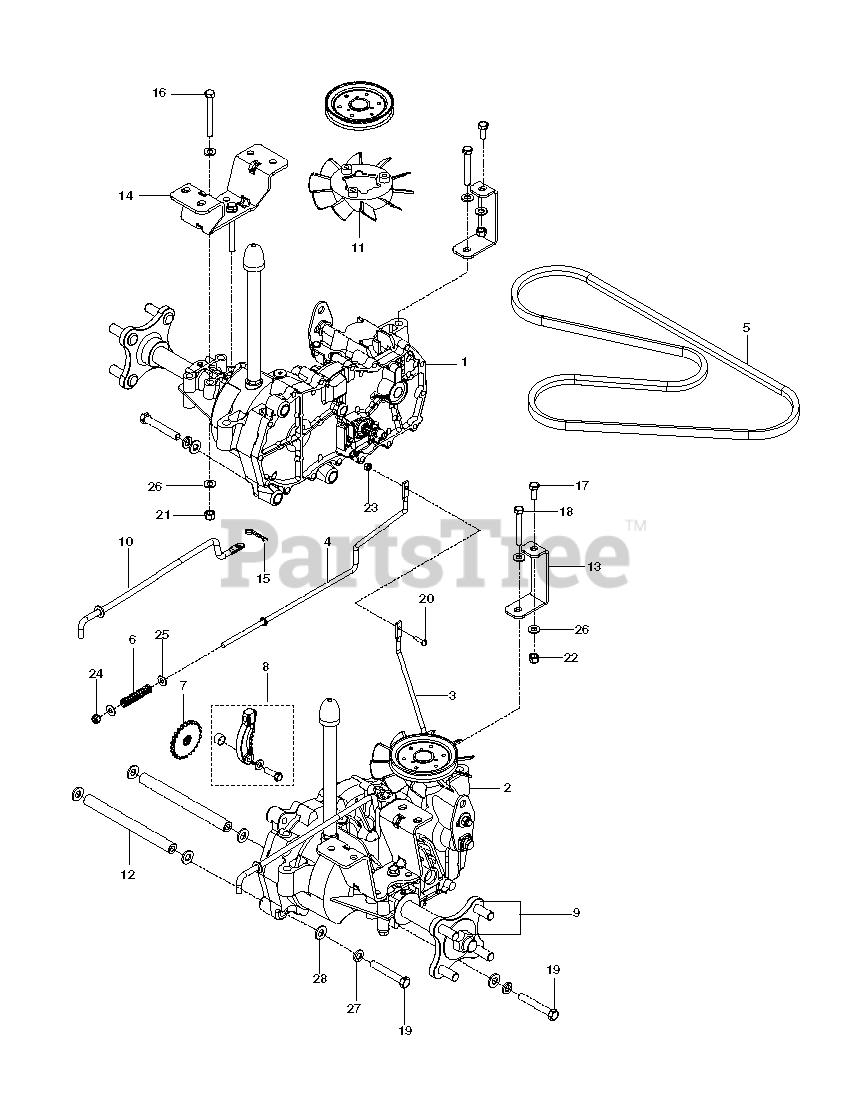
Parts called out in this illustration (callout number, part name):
1	HG_EZT, LT
2	HG_EZT, RT
3	LINKAGE.BRAKE.LT
4	LINKAGE, BRAKE RT
5	BELT, HYDRO PUMP
7	HG_DISC COG BRAKE
8	HG_KIT BRAKE ARM (EZT)
9	HG_KIT, HYDRO-GEAR HUB
10	LINKAGE, BYPASS, EZT
11	HG_HYDRO FAN
12	SPACER TUBE, EZT
13	SUPPORT FRT TRANS, BLK
14	EZT MOUNT, REAR, BLACK
15	HAIRPIN #2
16	HCS 5/16C X 2-3/4
17	HCS 5/16C X 3/4
18	CAPSCREW
19	HCS 3/8C X 2 1/2
20	SCR #10-24 X 3/4
21	NUT 5/16 NYLOC
22	5/16-18 THIN PROF NY
23	NUT 10-24 NYLOC
24	NUT 1/4-20 NYLOC
25	WASHER 1/4 SAE
26	FLAT WASHER 5/16 SAE
27	SLW 3/8 STD
28	WASHER 3/8 SAE FLAT
